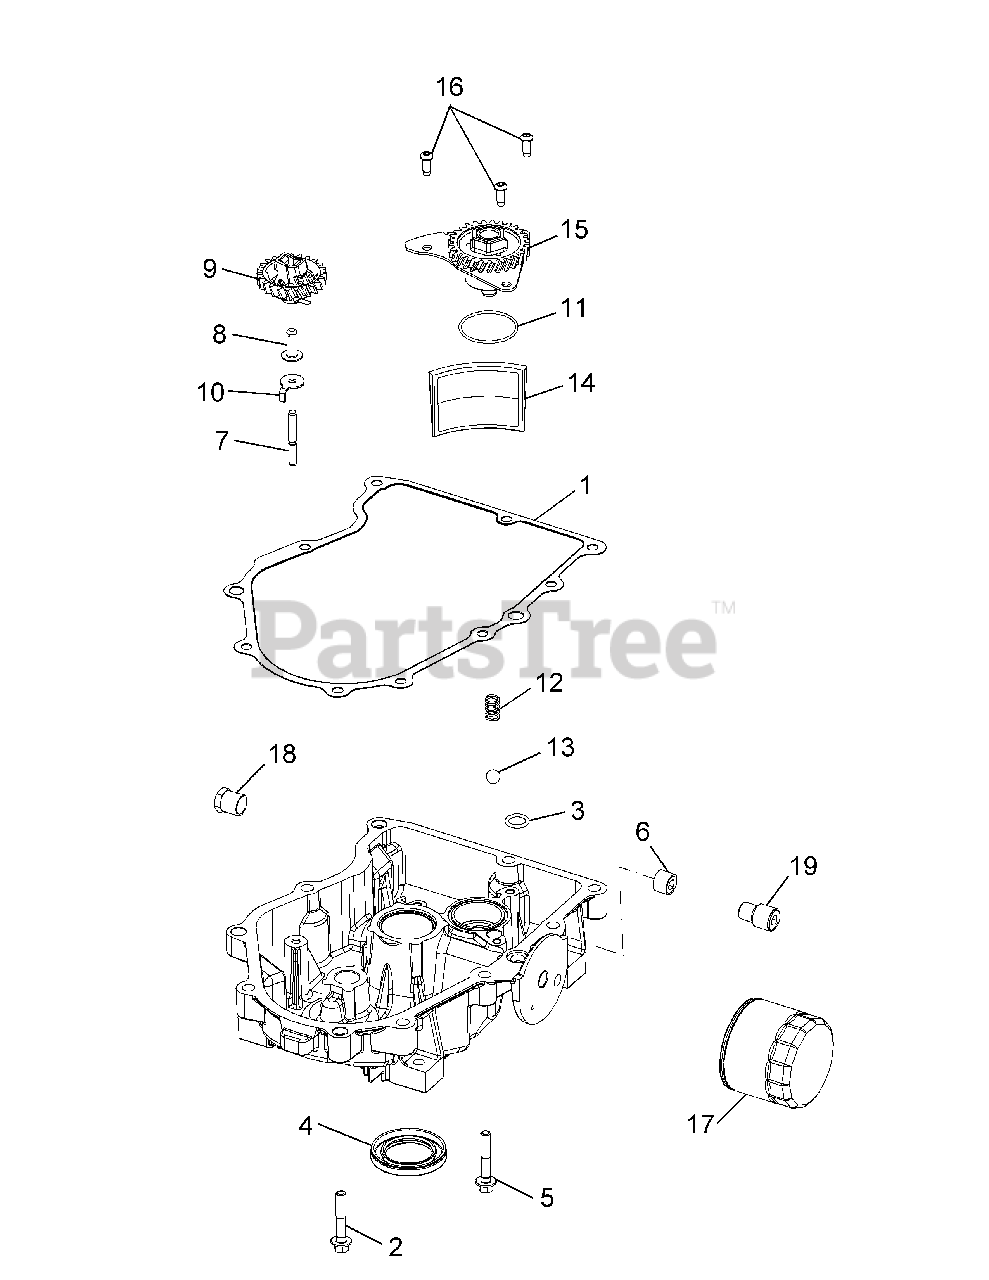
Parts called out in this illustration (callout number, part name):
1	Oil Pan Gasket
2	Flange Screw, M8 x 1.25 x .45
6	Pipe Plug, 3/8
7	Governor Gear Shaft
8	Governor Regulating Pin
9	Governor Gear Kit w/Pin
11	O-Ring (1.78" Dia.)
12	Compression Spring
13	Pressure Relief Ball
15	Oil Pump Assembly
16	Button Head Screw
18	Pipe Plug, 3/8
19	Oil Filter Nipple
